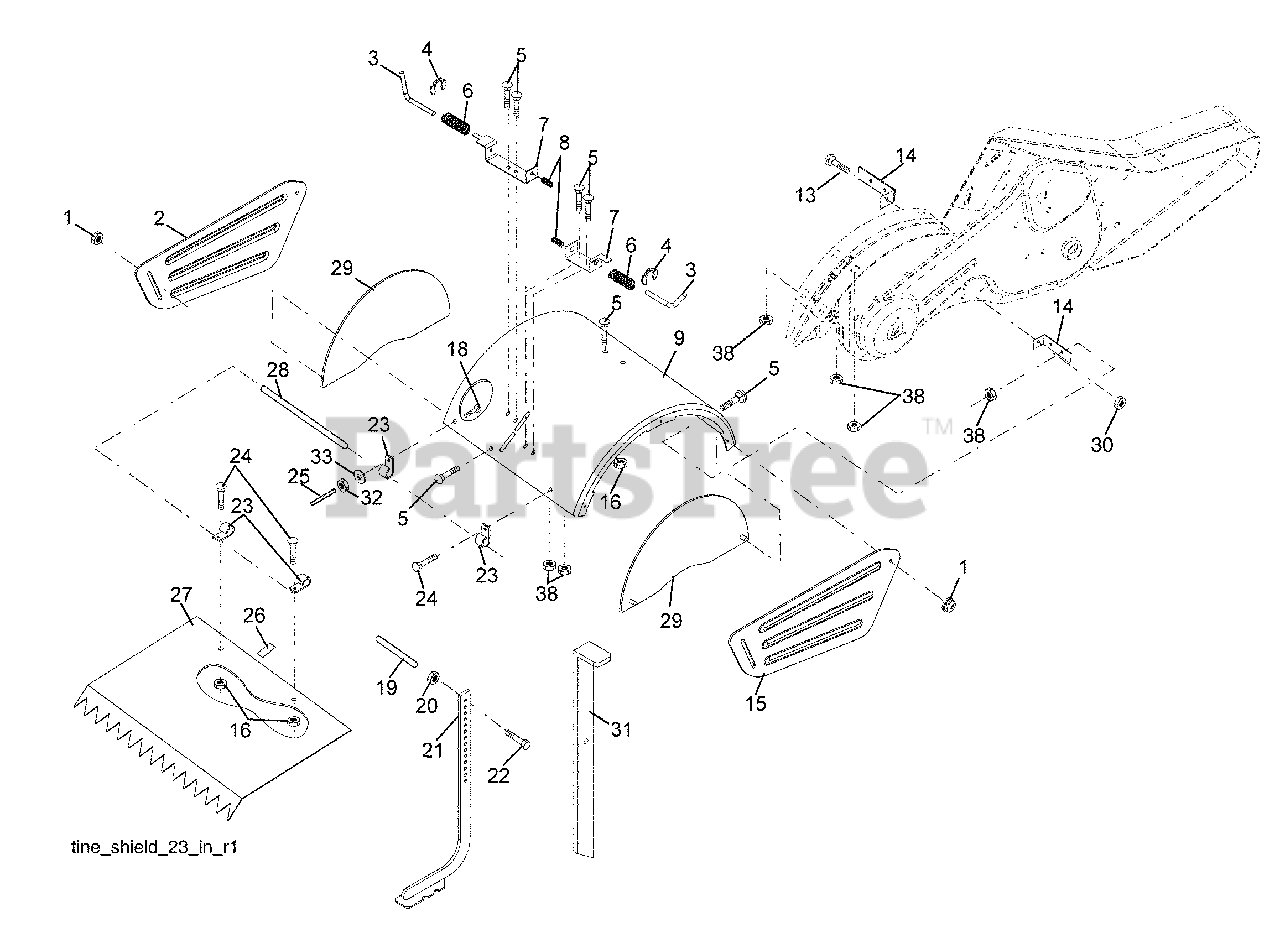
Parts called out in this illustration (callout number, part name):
1	Nut, Lock Hex Flange 5/16-18 unc
2	Shield, Side, Outer L. H.
3	Pin, Stake, Depth
4	Ring, Klip
5	Bolt Rdhd Sqnk 5/16-18 x 3/4
7	Bracket, Latch
8	Spring, Depth Stake
9	Shield, Tine
10	Bolt, Carriage 5/16-18 x 1-1/4
11	Bracket, Shield Tine
12	Shield, Side, Outer R.H.
13	Nut, Hex Flange 1/4-20
14	Bolt, Carriage 1/4-20 x 1-1/4 Gr. 5
16	Nut, Hex 3/8-16
17	Stake, Depth
18	Bolt, Hex 3/8-16 x 2
20	Bolt, Carriage 1/4-20 x 1/2
21	Cap, Vinyl
22	Pad, Idler
23	Shield, Leveling
24	Pin, Hinge
25	Nut Lock Flange
26	Shield, Side
27	Stake, Drag
28	Nut, Fin, Hex 1/4-20 unc
29	Washer Lock Hvy Helical 1/4
30	Nut Keps Hex 5/16-18 unc
